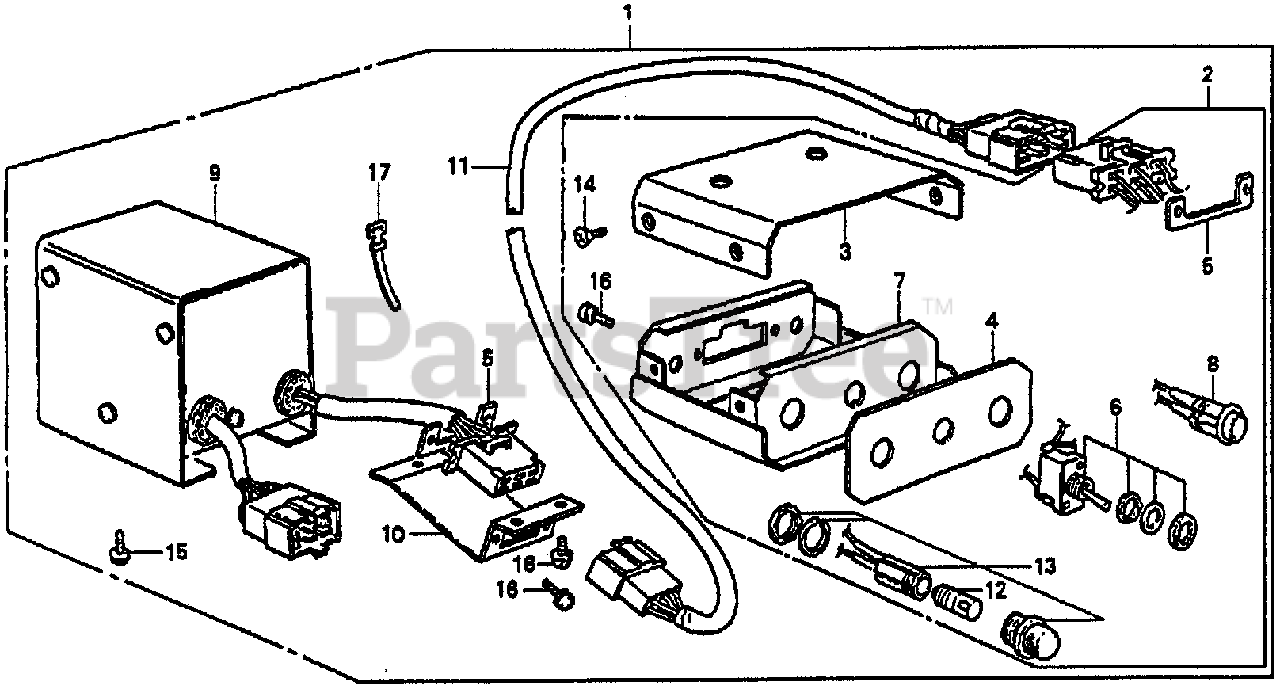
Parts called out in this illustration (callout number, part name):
1	CONTROL KIT, REMOTE
2	BOX ASSY., SWITCH
3	COVER (UPPER)
4	PANEL, FR.
5	PLATE, CONNECTOR SETTING
6	SWITCH, TOGGLE
7	CASE, SWITCH
8	SWITCH, PUSH
9	BOX ASSY., RELAY
10	HOLDER, CONNECTOR
11	CABLE, REMOTE CONTROL
12	BULB, DASH (24V-2W)
13	SOCKET ASSY., PILOT LAMP
14	SCREW, FLAT (4X8)
15	SCREW-WASHER (5X12)
16	SCREW-WASHER (4X12)
17	BAND B1, CABLE
